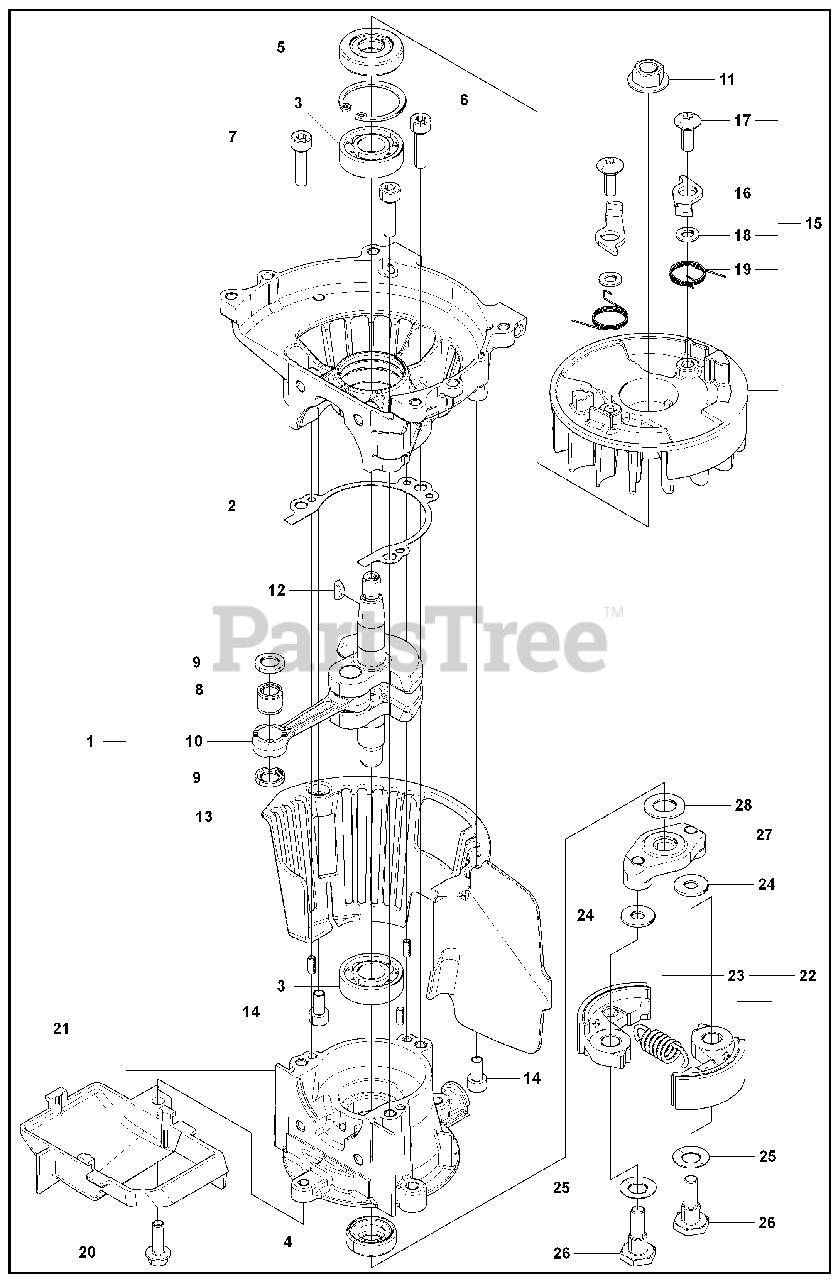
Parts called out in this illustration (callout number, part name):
1	CRANKCASE COMP.
2	GASKET, case
4	SEAL
7	BOLT TORX M5xL20 T27
9	WASHER
10	CRANKSHAFT COMP.
11	NUT M8xP1.0
14	BOLT TORX M5xL10 T27
15	ROTOR ASSY
18	WASHER 5x10x10
20	BOLT TORX
22	SHOE COMP.
27	PLATE, clutch
